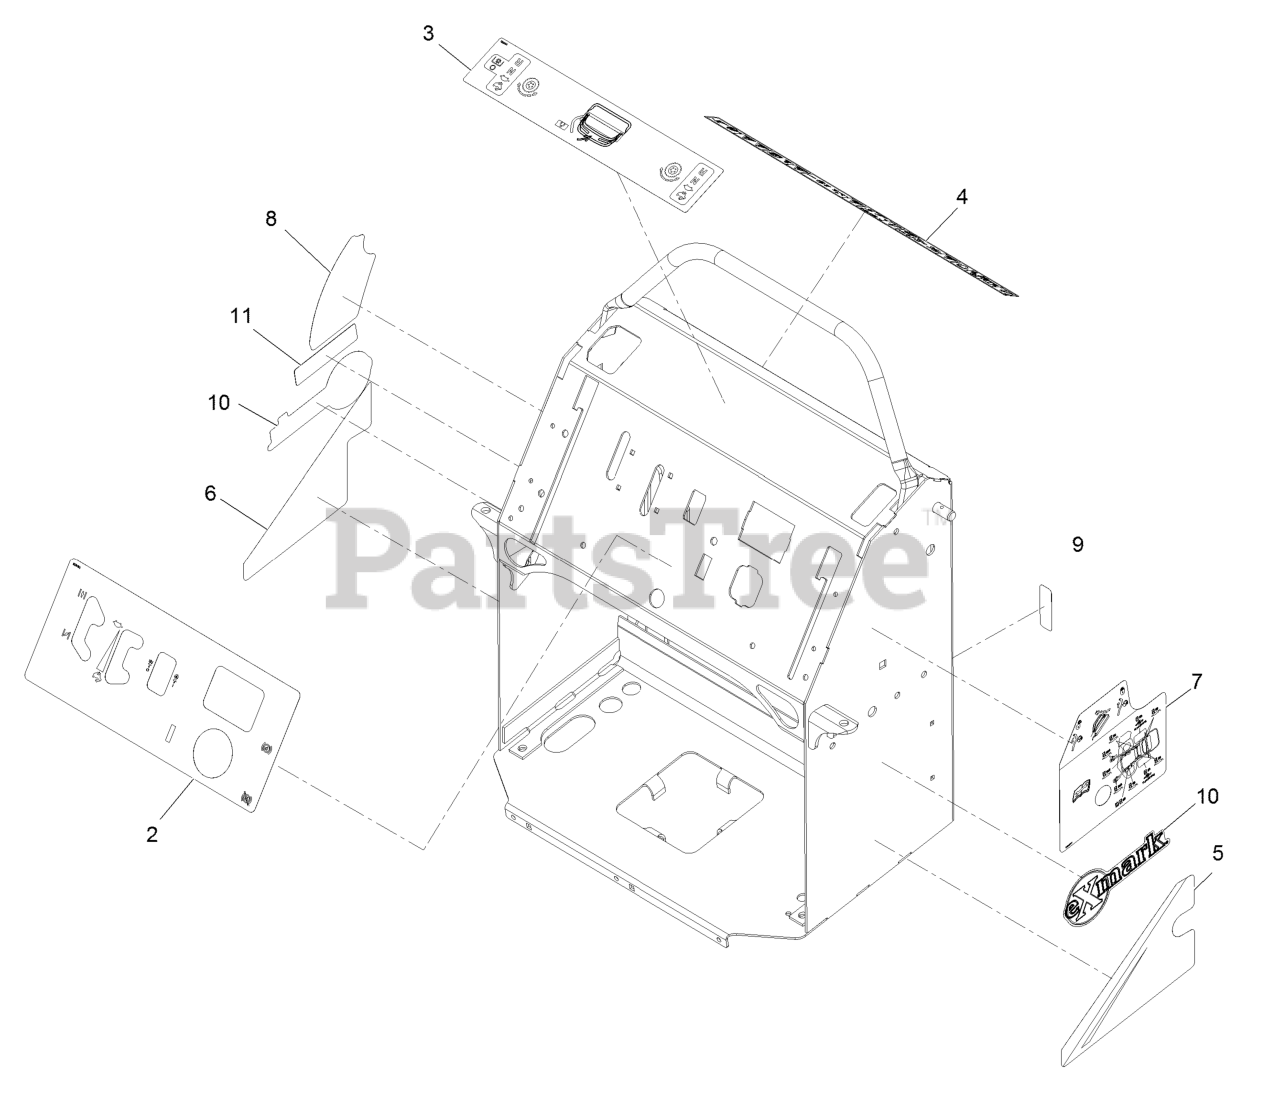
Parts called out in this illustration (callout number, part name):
2	Decal-Control Panel Efi
3	Decal-Motion Control
4	Decal-Warning
5	Decal-LH Panel
6	Decal-RH Panel
7	Decal-Service Aid
8	Decal-Height Of Cut
9	Decal-Fuse
10	Decal-Exmark Logo
11	Decal-Arrester, Spark
